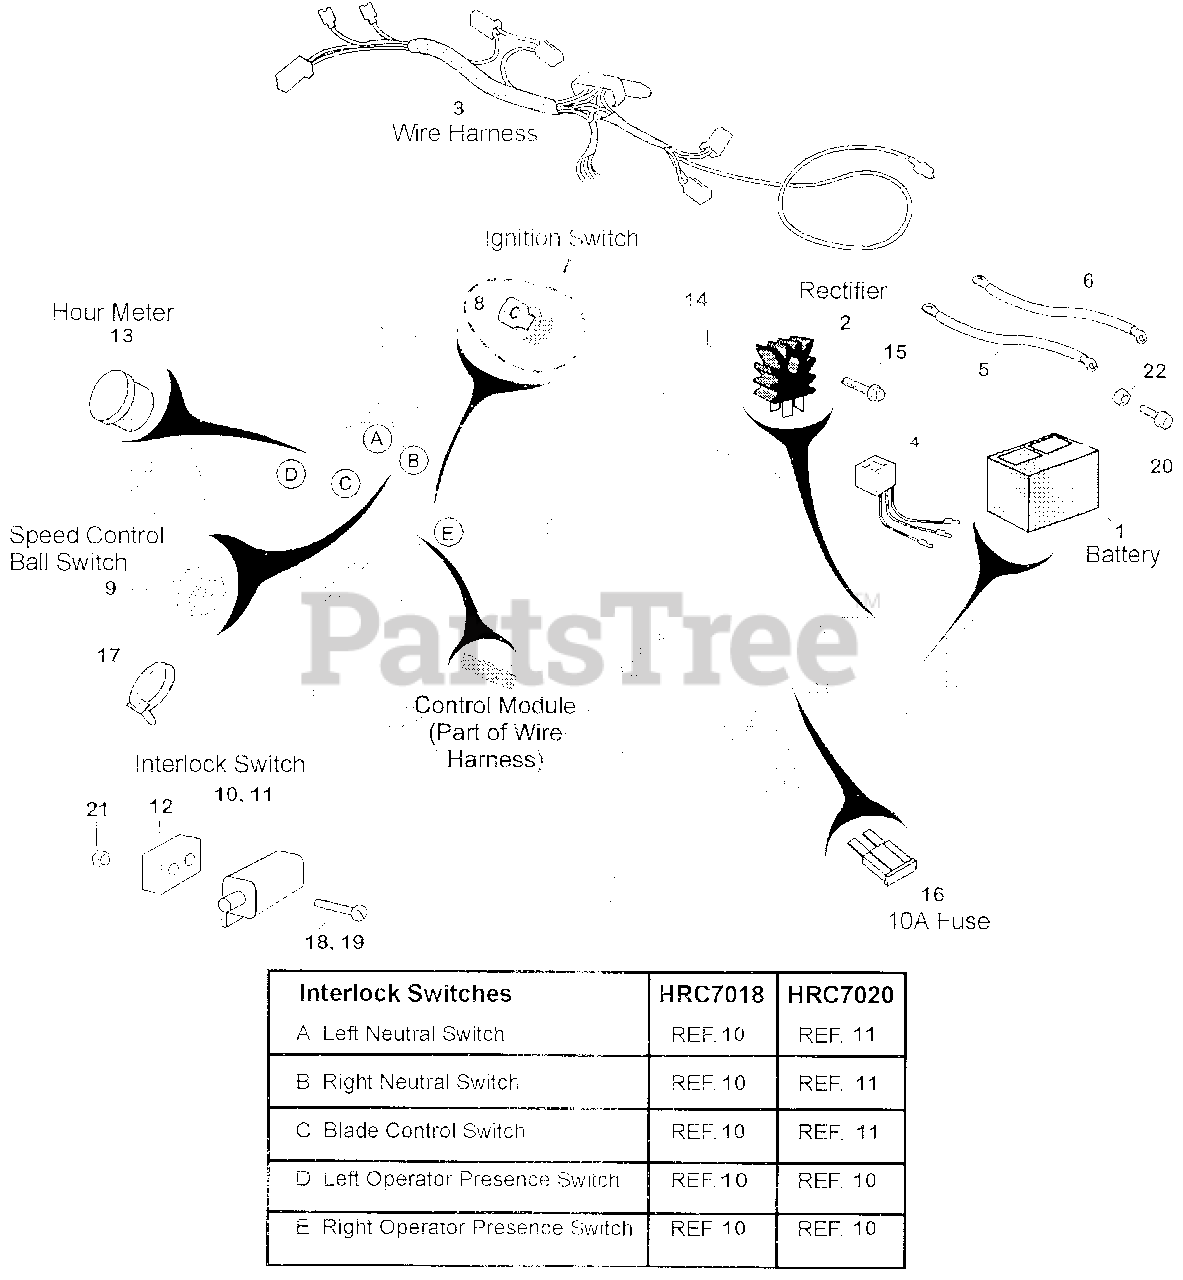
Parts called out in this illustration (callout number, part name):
3	WIRE HARNESS ASSY.
7	SWITCH ASSY., COMBINATION
8	KEY, IGNITION
9	SWITCH, BALL
10	LIMIT, SWITCH
12	SPACER, SWITCH
13	METER ASSY., HOUR
